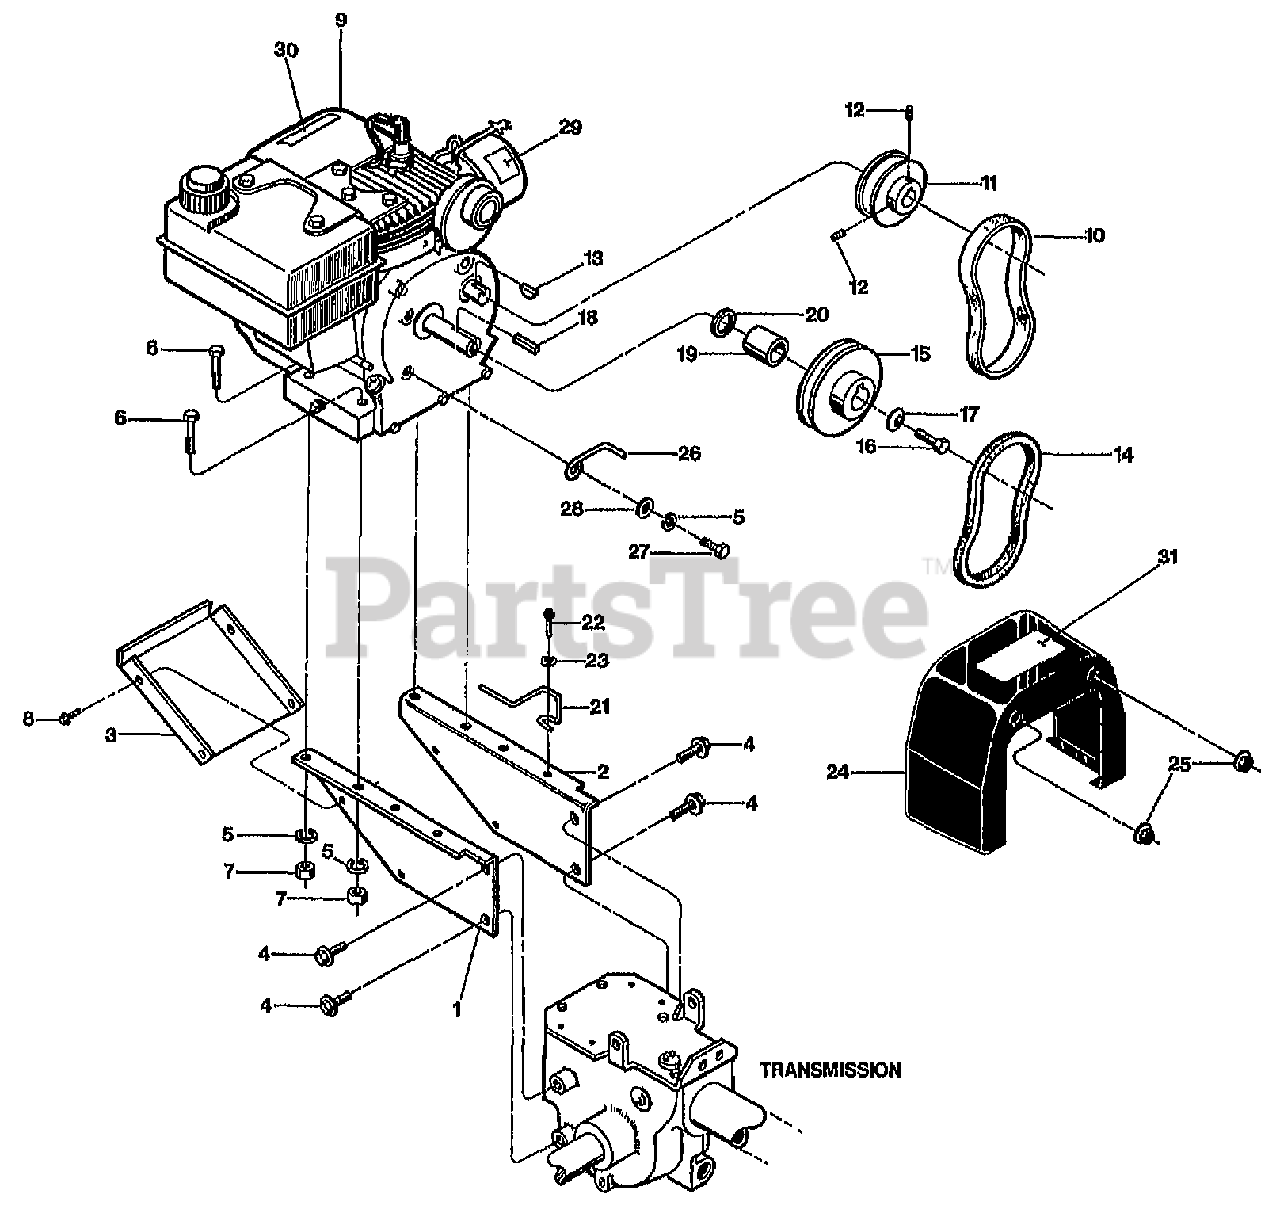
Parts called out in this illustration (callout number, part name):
1	BRKT-ENG LT P4
2	BRKT-ENG RT PNT
3	PAN-ENG BRKT PNT
4	SCR-HFLK 5/16-18X.75
5	WASHER-LK .312
6	SCR-HH 5/16-18X1.5 G5
7	NUT-HEX 5/16-18
8	SCR-HH SEMS 10-32 X .5 (W/PERMANET WASHER)
9	ENGINE, TECUMSEH HP,
10	BELT-FLAT (SEE BELT SET BELOW)
11	PULLEY-REV DRILL/TAP (INCL. 10)
12	SCR-SS 1/4-20 X .25 (SECURES REVERSE ENGINE PULLEY)
13	KEY-WOODRUFF #5, REVERSE PULLEY TO REVERSE PTO SHAFT
14	BELT-V GROOVE FWD SMFRAME
15	PULLEY-ENGINE MACH
16	SCR-HH 3/8-24X1.0 G5
17	WASHER-.994X.413X.145 (CONCAVE SURFACE FACES FORWARD PULLEY)
18	KEY-.188 SQX1.0
19	SPACER-.938X.755X1.44 (ON FORWARD PTO SHAFT BETWEEN ENGINE AND SPACER)
20	SHIM-1.0X.7656X.031 (ON FORWARD PTO SHAFT BETWEEN ENGINE AND SPACER)
21	GUIDE-BELT FWD
22	SCR-HWH 1/4-20 X .75 STH
23	WASHER-FLAT 1/4 SAE
24	COVER-BELT W/DECAL (INCL. 31)
25	NUT-HFLK 5/16-18
26	STOP-BELT
27	SCR-HH 5/16-24X.75 G5
28	WASHER-FLAT 5/16 SAE
29	DECAL-HOT SURFACE
30	DECAL-STARTING STABIL
31	DECAL-BELT COVER OPC
